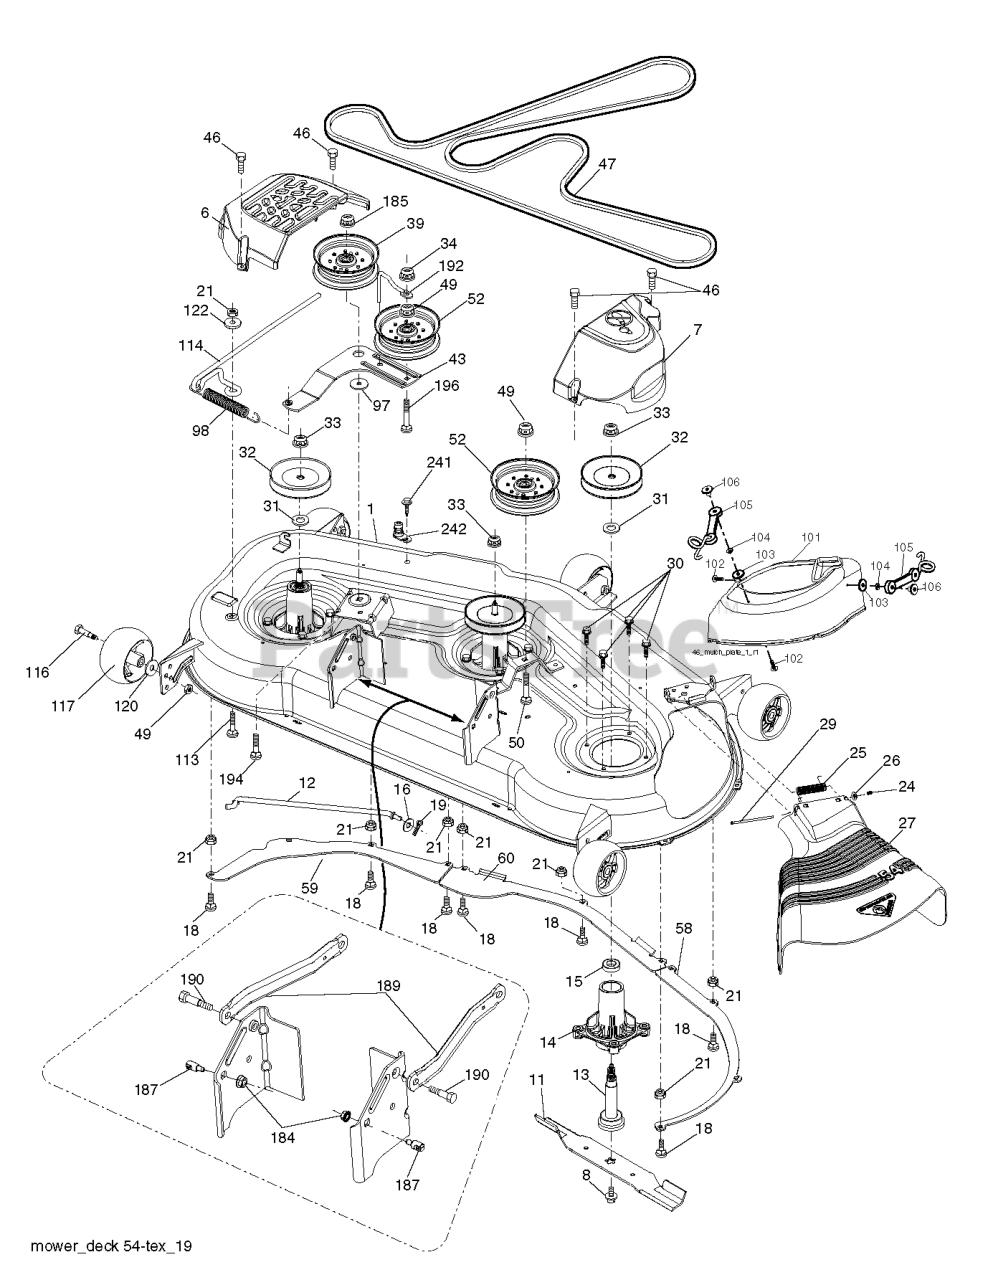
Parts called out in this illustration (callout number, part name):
1	DECK.WELDMENT.54"MS-498
6	COVER.MANDREL.LH.54"20
7	COVER.MANDREL.RH.54.20
8	BOLT.WASHER.ASM.7/16-2
11	BLADE.BAGGING.54"
11	54" MULCH BLADE
12	ROD.ANTI.SWAY.48/54"K4
13	SHAFT ASM MANDREL
14	RP.HOUSING.MANDREL.4PT.
16	WASHER
18	BOLT
19	PIN.COTTER.5/16.BOW TI
21	LOCKNUT
24	CAP-SLEEVE LT
25	SPRING, TORSION
26	NUT PUSH M
27	DEFLECTOR
29	ROD.HINGE
30	SCREW, WASHER HEAD
31	WASHER.SPACER.MANDREL
32	PULLEY/MANDREL
33	NUT.FLANGE.LOCK.TOP
39	RB PULLEY.IDLER.4.50/HUB SPEC
43	ARM.IDLER
46	SCREW.1/4-20X5/8
47	RP.BELT.DRIVE.54."2006
49	NUT LOCK FLG 3/8-16 UNC
50	BOLT
52	PULLEY.IDLER.2006
58	BAFFLE.RIGHT.54"
59	BAFFLE.LEFT.54"
60	BAFFLE CENTER 54" MOWER
98	SPRING, DECK DRIVE
101	MULCH COVER 54"
102	SCREW
104	LOCKWASHER #10
105	LATCH ASSY
106	WELDNUT
113	BOLT CRT
114	ROD TENSION RELIEF
116	BOLT.SHOULDER.3/8-16X3-5/8.
117	RP WHEEL. GUAGE RALLY
120	WASHER
122	BUSHING.RELIEF.TENSION
184	NUT LOCK HEX FLANGE 5/16-18
185	NUT.LOCK.FLANGE.7/16
187	STUD.FASTNER.W/ANTI-ROTATE
189	ARM.SUSPENSION.MOWER
190	BOLT.SHOULDER
192	KEEPER.BELT.IDLER.54"T
194	BOLT.HEX.WASHER.HEAD.7/16-24X
196	BOLT
241	SCREW.TT.#10-32X.5.3/8.FLANGE
242	PORT.WASHOUT
